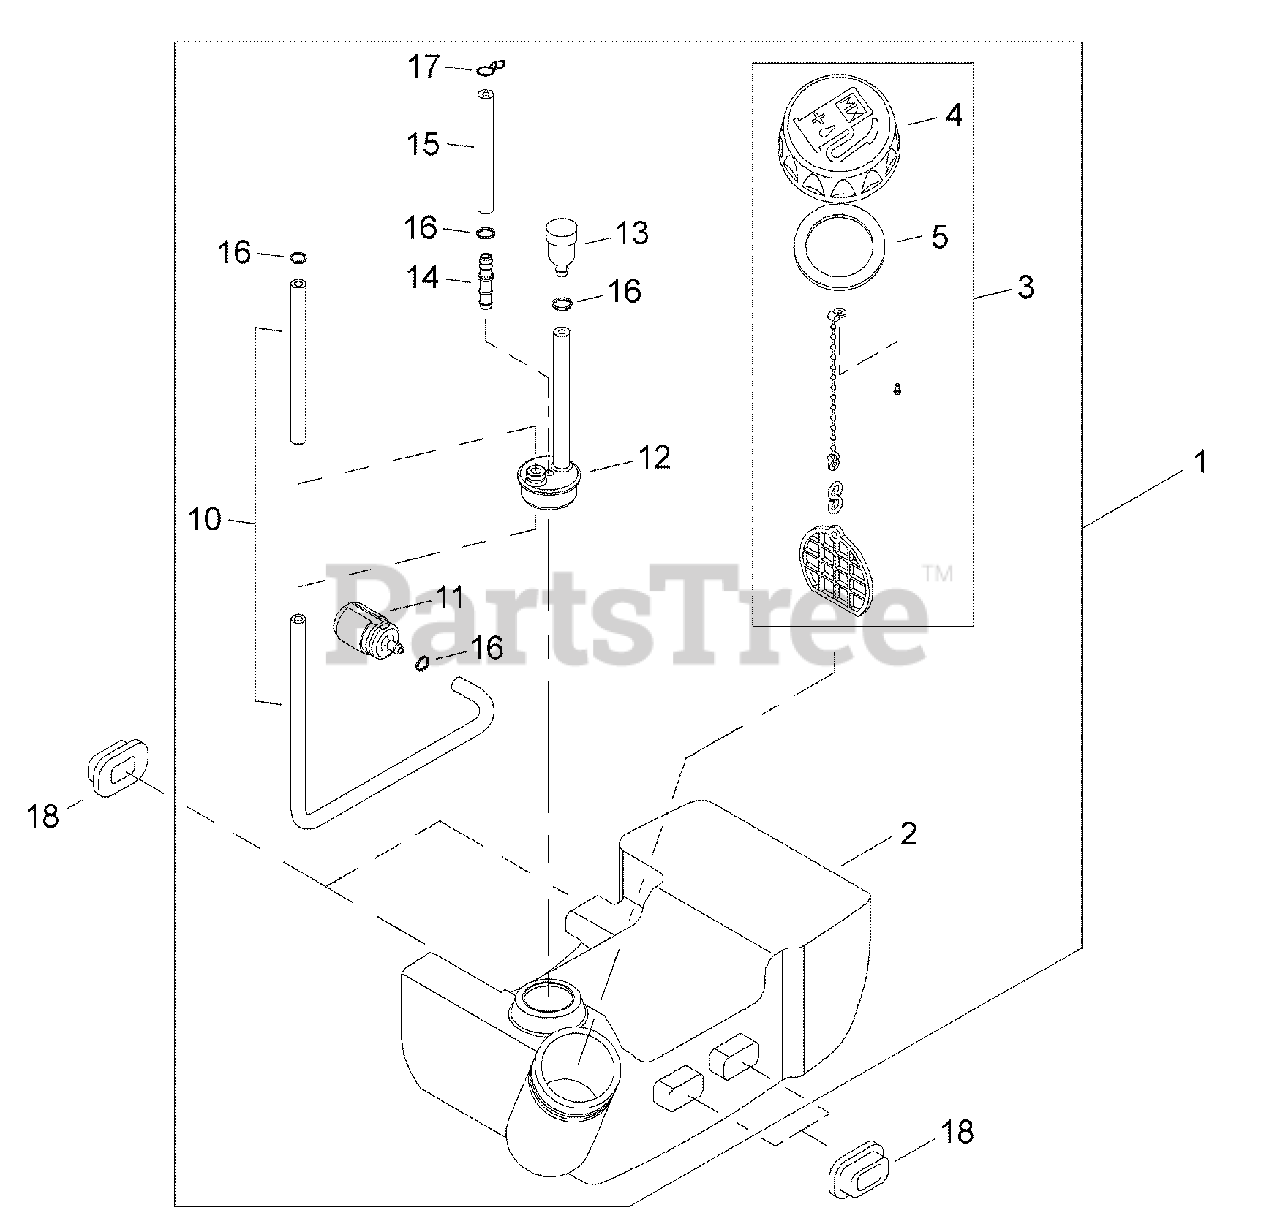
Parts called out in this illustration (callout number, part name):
1	TANK ASSY, FUEL
2	TANK, FUEL
3	CAP ASSY, FUEL
4	CAP, FUEL
5	GASKET, FUEL CAP
10	PIPE, FUEL
11	FILTER, FUEL 125-528
12	GROMMET, FUEL W/VENT PIPE
13	VENT ASSY
14	CONNECTOR, PIPE
15	PIPE, FUEL RETURN
16	CLIP Ø6
17	CLIP, SPRING Ø5.2
18	CUSHION, FUEL TANK
